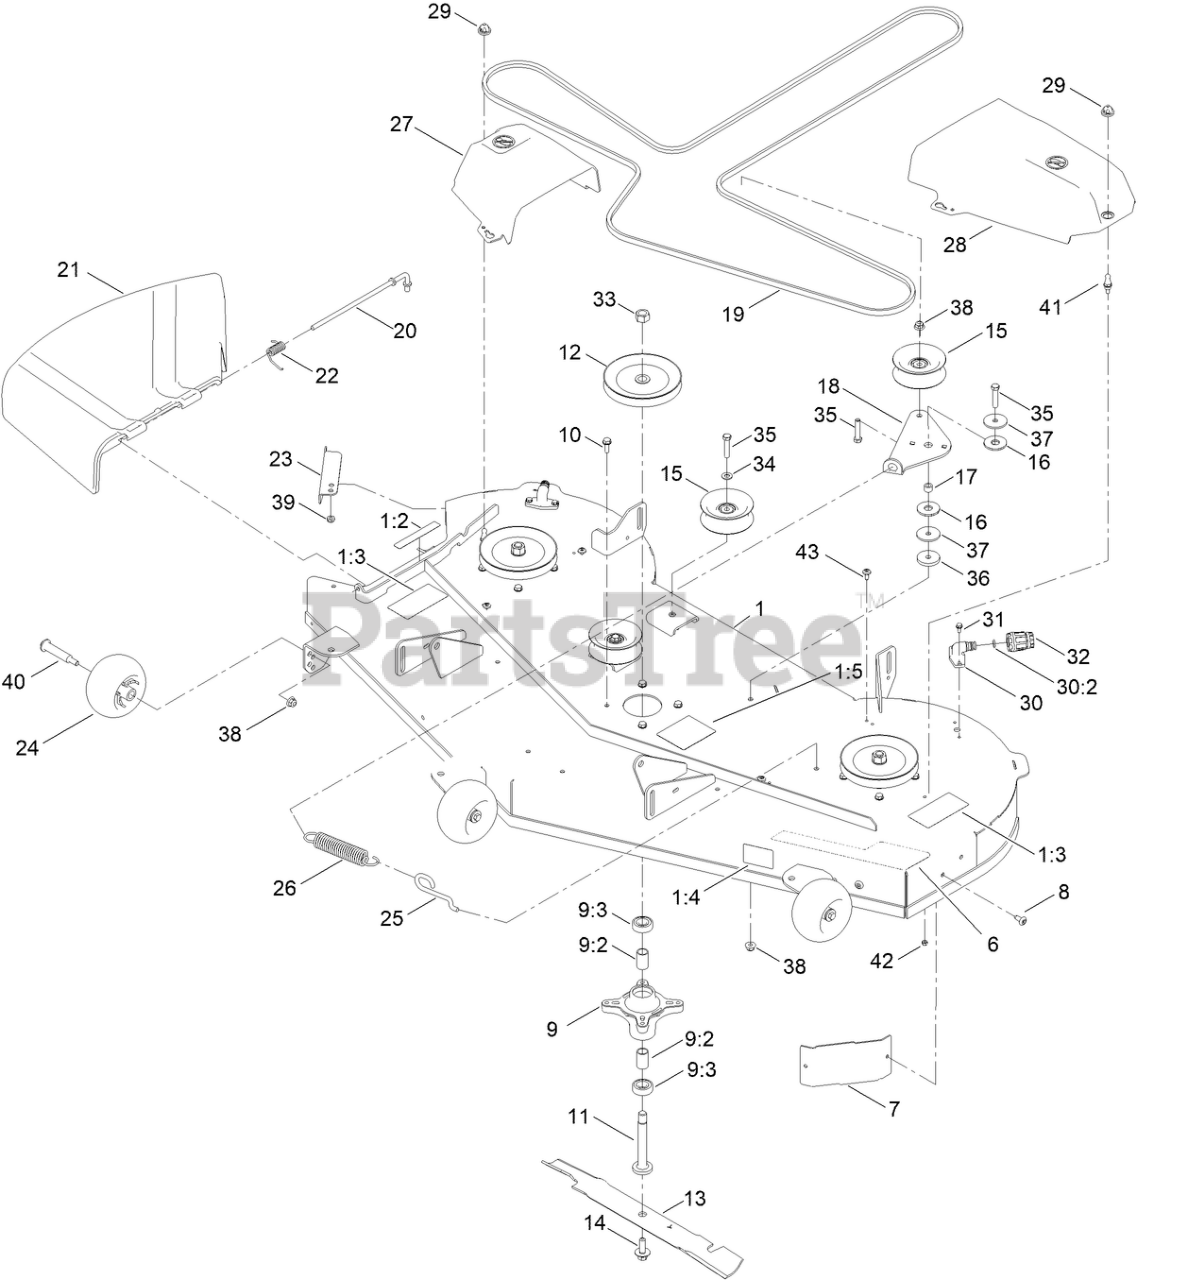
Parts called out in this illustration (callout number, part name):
1	60 IN DECK DECAL ASM
1:2	DECAL-DANGER
1:3	DECAL-DANGER, DECK
1:4	DECAL-SCALP, ANTI
1:5	DECAL-ROUTING, BELT
6	DECAL - IRON FORGED 60
7	BAFFLE-CORNER
9	SPINDLE ASM
9:2	SPACER
9:3	BEARING-BALL
10	SCREW-TAPTITE
11	SHAFT-SPINDLE
12	PULLEY
13	BLADE-HI FLOW, 20.5 INCH
14	BOLT-BLADE, SEMS
15	PULLEY-IDLER, FLAT
16	WASHER-FRICTION, COMPOSITE
17	SPACER
18	ARM-IDLER
19	BELT-V (A SEC, 154.96 EL)
20	ROD-PIVOT
21	DEFLECTOR-DISCHARGE
22	SPRING-TORSION
23	BAFFLE-CUTOFF
24	ROLLER-SCALP, ANTI
25	HOOK-RETURN SPRING
26	SPRING-EXTENSION
27	COVER-BELT, RH
28	COVER-BELT, LH
29	GROMMET-BALL
30	FITTING-WASHOUT
30:2	O-RING
31	SCREW-HWH
32	CONNECTOR-HOSE
33	NUT-HEX
34	WASHER-FLAT
35	SCREW-HH
36	WASHER-PLAIN
37	WASHER-REBOUND
38	NUT-HF, NI
40	BOLT-SHOULDER
41	STUD-BALL
42	NUT-LOCK
43	SCREW-SHOULDER
